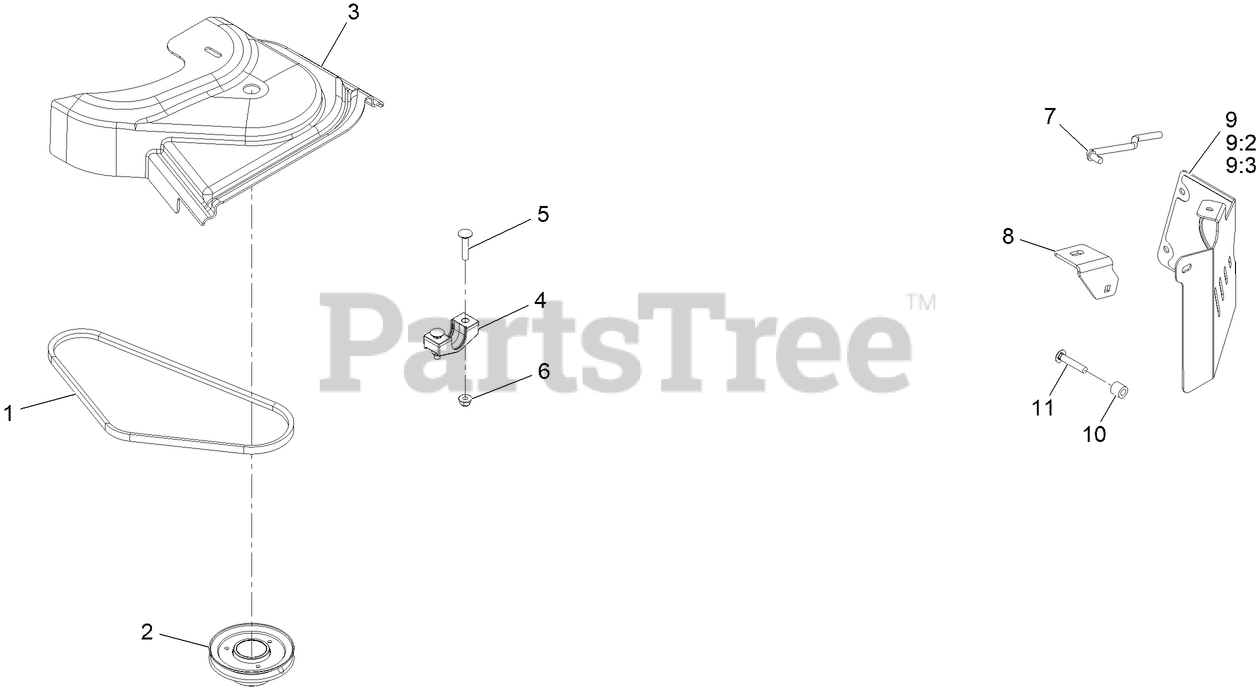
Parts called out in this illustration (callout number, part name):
2	SHEAVE,DRIVE LZUV 606
3	COVER,BELT UV 60
4	SUPPORT-BEARING CROSS SHAFT
5	SCREW-CARR
6	NUT-HF, NI
7	LINK-HANDLE
8	BRACKET-HANDLE MOUNT
9	PANEL ASM, BAGGER LH QUARTER
9:2	DECAL-WARNING
9:3	Shield-Bagger LH Quarter Panel
11	BOLT-CARRIAGE
